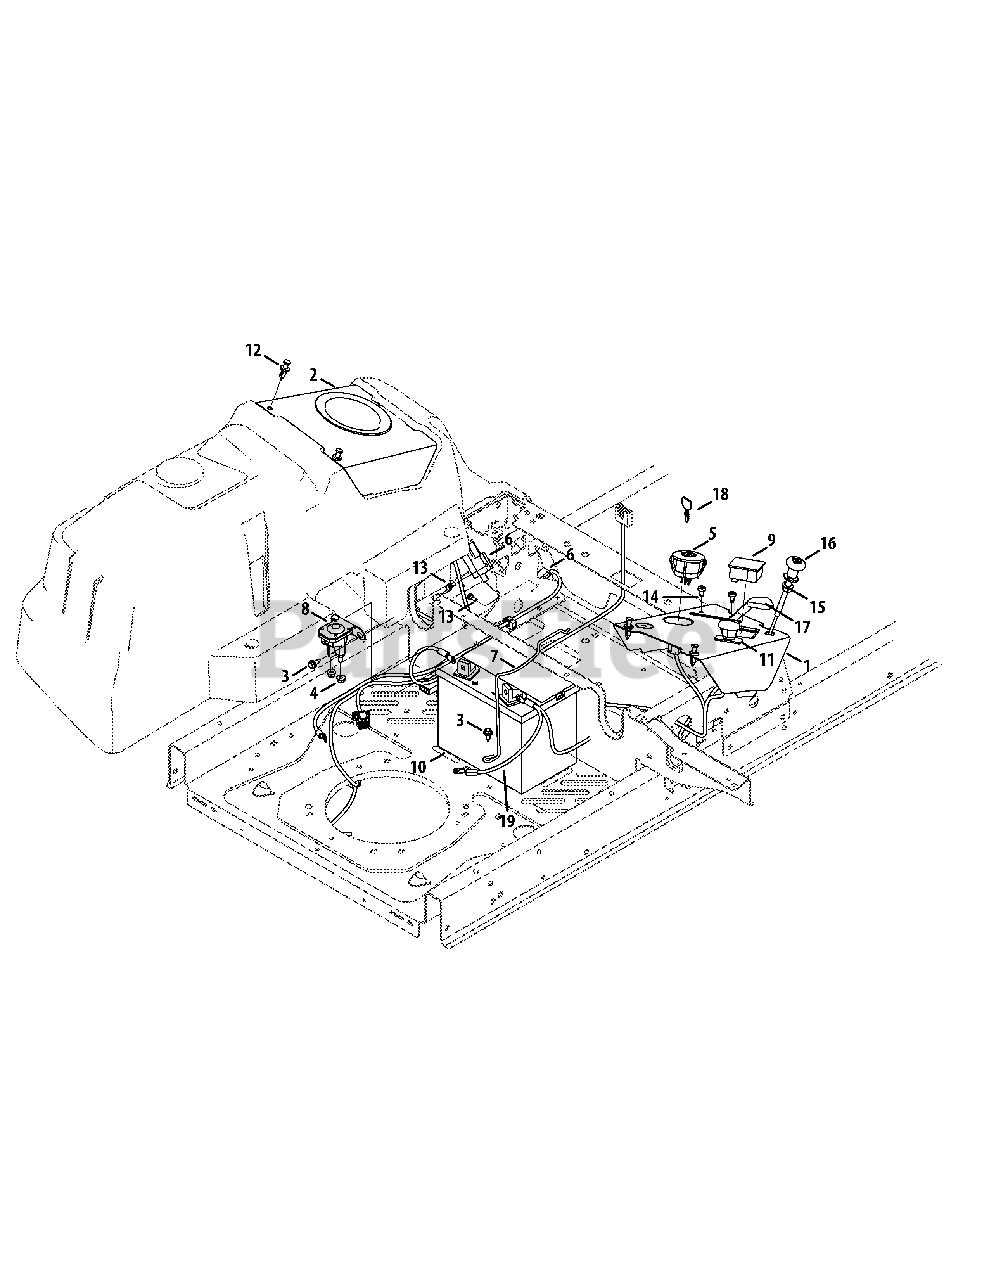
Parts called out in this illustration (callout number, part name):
1	Console Cover, RH
2	Console Cover, LH
3	Hex Washer Screw, 1/4-20 x .625
4	Flange Lock Nut, 1/4-20
5	Key Switch
6	Interlock Switch
7	Battery Rod
8	Solenoid
9	Hour Meter/Service Minder
10	Battery
11	Electric PTO Switch
12	Plastic Rivet
13	Shoulder Screw, #10-32 x .500
14	Screw, 1/4-20 x .50
15	Flange Lock Nut, 3/8-16
16	Choke Cable
17	Throttle Cable
18	Key, Assembly
19	Harness Assembly
